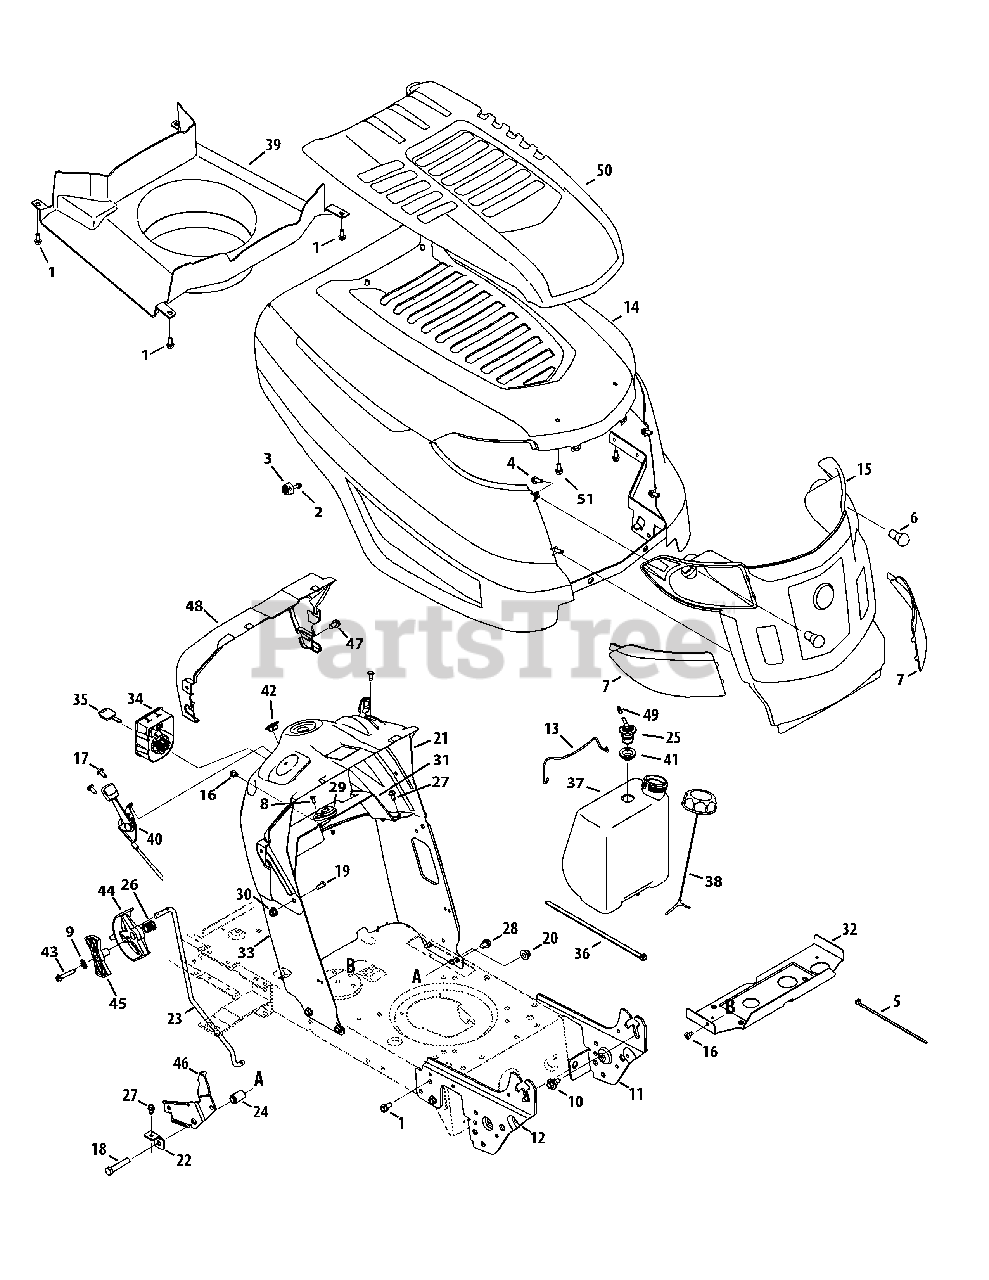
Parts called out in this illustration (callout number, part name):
1	Screw 5/16-18 x .750
2	Screw, #12-16 x 1.25
3	K-Style Bumper
4	Screw, 1/4 x .750
5	Cable Tie
6	Miniature lamp 12V socket
7	Grill Lens - LH
7	Grill Lens - RH
8	Screw, #10-16 x .500
9	Lock Washer, 1/4
10	Shoulder Screw .43 x .29
11	Suppport Bracket LH
12	Suppport Bracket RH
13	Battery Rod
14	Hood, w/ scoop
15	Grille Assembly, K-Style
16	Screw, 1/4-20 x .500
17	Screw 1/4-20 x .500
18	Hex Screw 3/8-16 x 2.00
19	Hex Screw, 5/16-18 x .625
20	Flange Lock Nut 3/8-16
21	Dash, Upper,
22	Speed Latch Tab
23	Speed Control Rod
24	Flange Spacer .39 x .671 x 1.095
25	Rollover Valve
26	Compr. Spring, .72 OD x .78
27	Tap Screw, 1/4-20, 0.625
28	Screw 5/16-18 x .625
29	Bearing, .628 ID x 1.36
30	Flange lock Nut 5/16-18
31	Bracket, Steering Support
32	Gas Tank Support Bracket
33	Dash, Lower NWNDW
34	Key Switch Module
36	Cable Tie
37	1.36 Gallon Fuel Tank
38	Fuel Cap, 2.25"
39	Plenum
40	Throttle/Choke Cable, 28"
41	Rubber Grommet, 23 x 3.55
42	Choke Plug
43	Hex Washer Screw, 1/4-20 x 1.50
44	Shift Lever
45	Index Control
46	Transmission Speed Latch, RMC
47	Screw, 1/4-15 x .750
48	Dash Collar
49	Hose Vent, 3/16 EPA
50	Hood Scoop
51	Screw, 1/4-15 x 0.50
